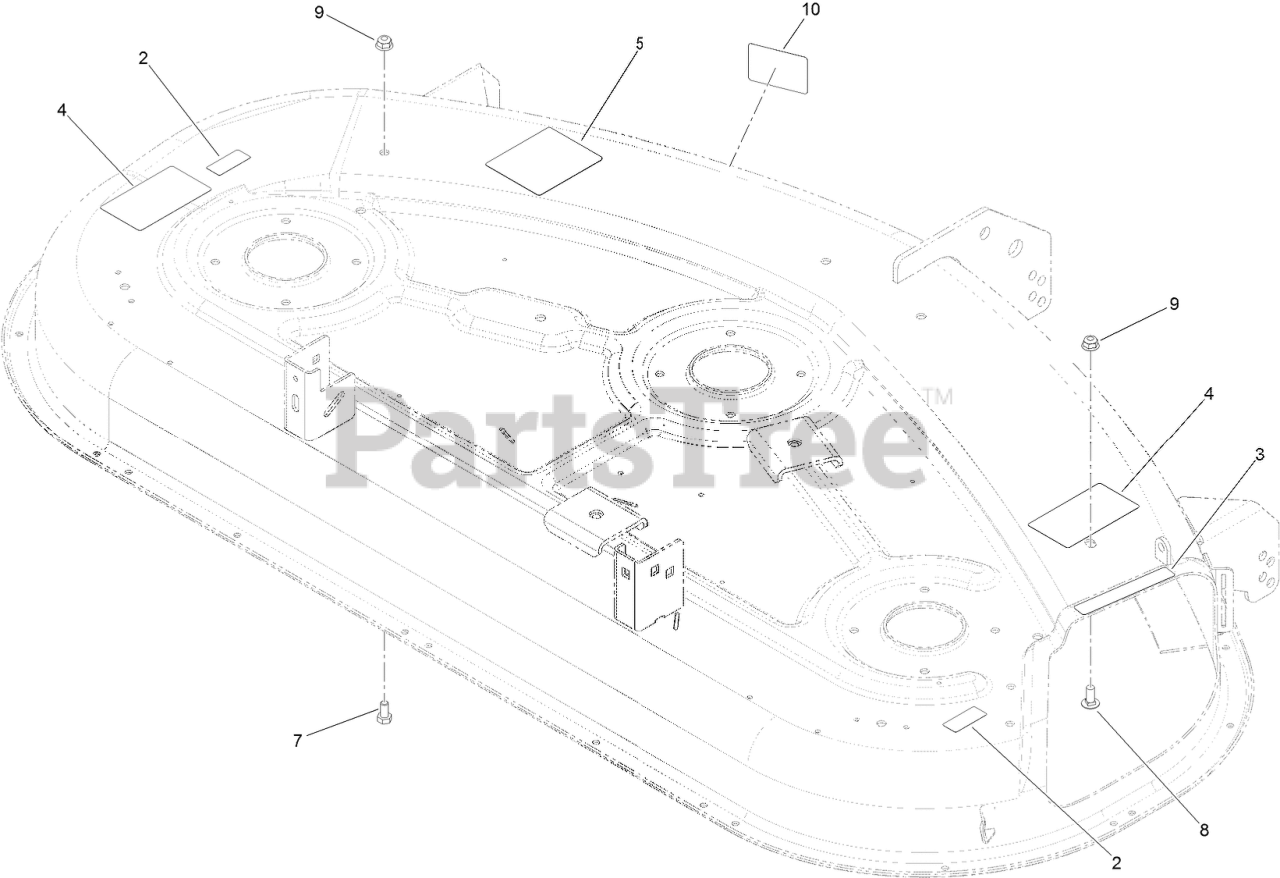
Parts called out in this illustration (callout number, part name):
2	DECAL-DANGER
3	DECAL-DANGER
4	DECAL-DANGER
5	DECAL-ROUTING, BELT
7	SCREW-HH
8	SCREW-CARR
9	NUT-HF, NI
10	DECAL-SCALP, ANTI
